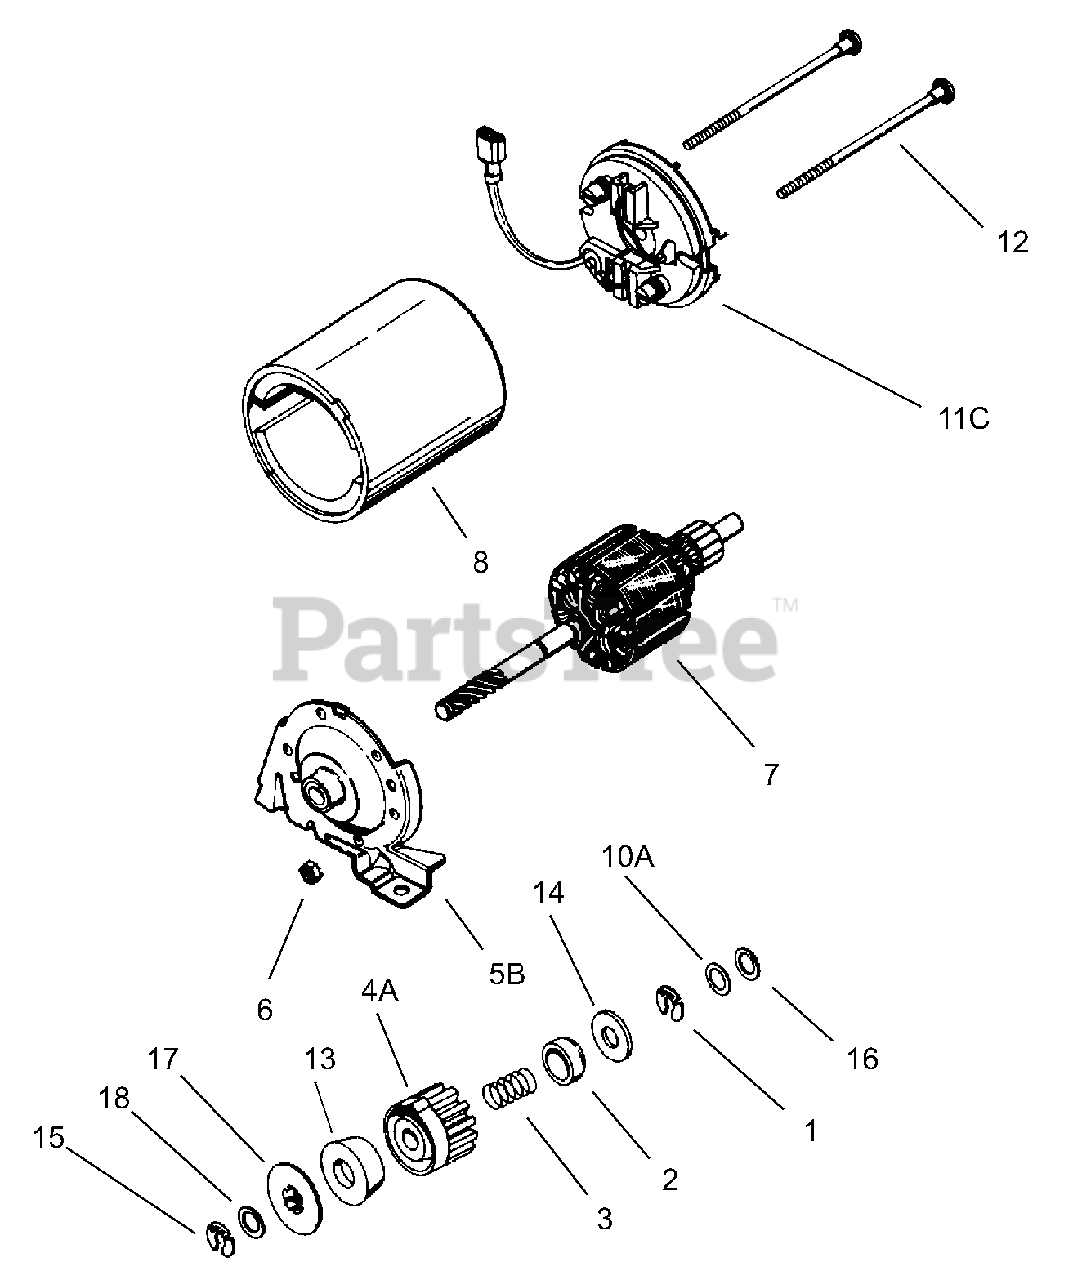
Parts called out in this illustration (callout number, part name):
1	Ring-Retaining
2	Spring-Retainer
3	Spring
4A	Gear
5B	Drive End Cap ASM
6	Nut-Lock
7	Armature
8	Housing ASM
10A	Washer-Thrust
11C	Commutator End Cap ASM (Incl. Brushes)
12	Bolt
13	Driver-Pinion
14	Washer-Cup
15	Ring-Retaining
16	Washer
17	Nut-Drive
18	Washer
